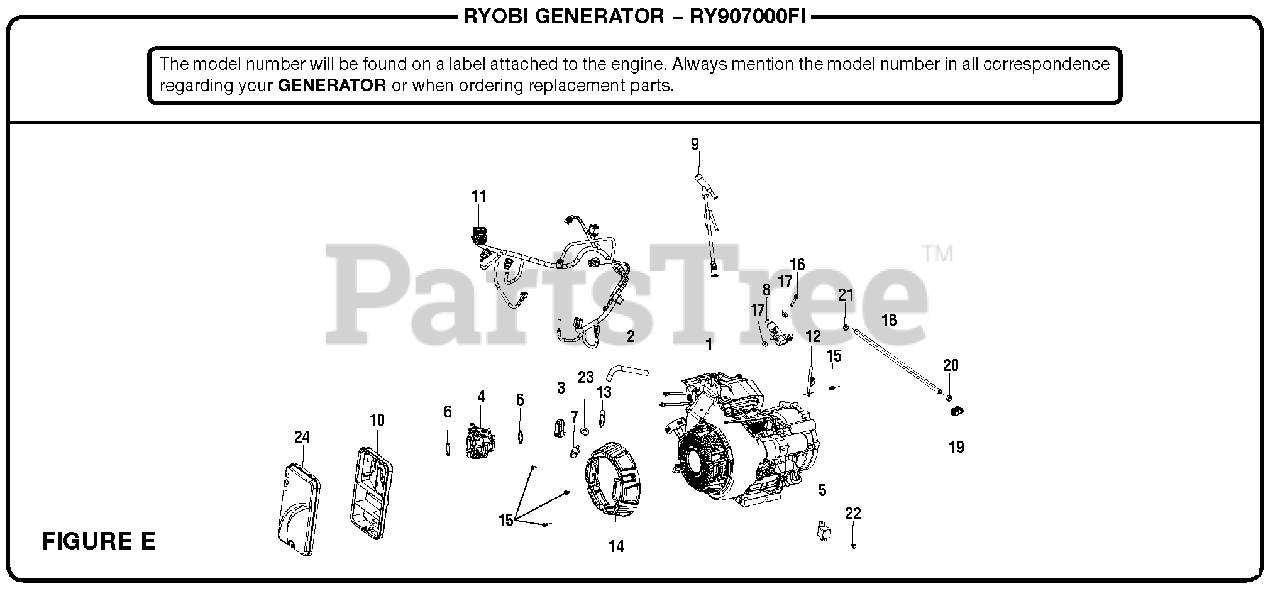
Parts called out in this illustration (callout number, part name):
1	R420 EFI Engine (Longblock)
2	Crankcase Vent Hose
4	Throttle Body Assembly
5	Starter EFI Relay
7	Head Temperature Sensor
8	Ignition Coil
9	High Tension Wire Assembly
10	Rear Airbox w/ Bushings Assembly
11	EFI Wire Harness
12	J-Clamp Flexible
13	EFI Intake Gasket
14	Recoil Cover
15	Bolt (M5 x 10 mm, Hex Hd.)
16	Bolt (M6 x 42 mm,T30 Torx Pan Hd.)
18	Fuel Hose (440 mm)
19	Fuel Quick Connect 90
20	Injector Fuel Clamp
21	Fuel Hose Ear Clamp
22	Bolt (M6 x 10mm, Hex Hd.)
23	Washer (1/2)
24	Front Airbox Cover
